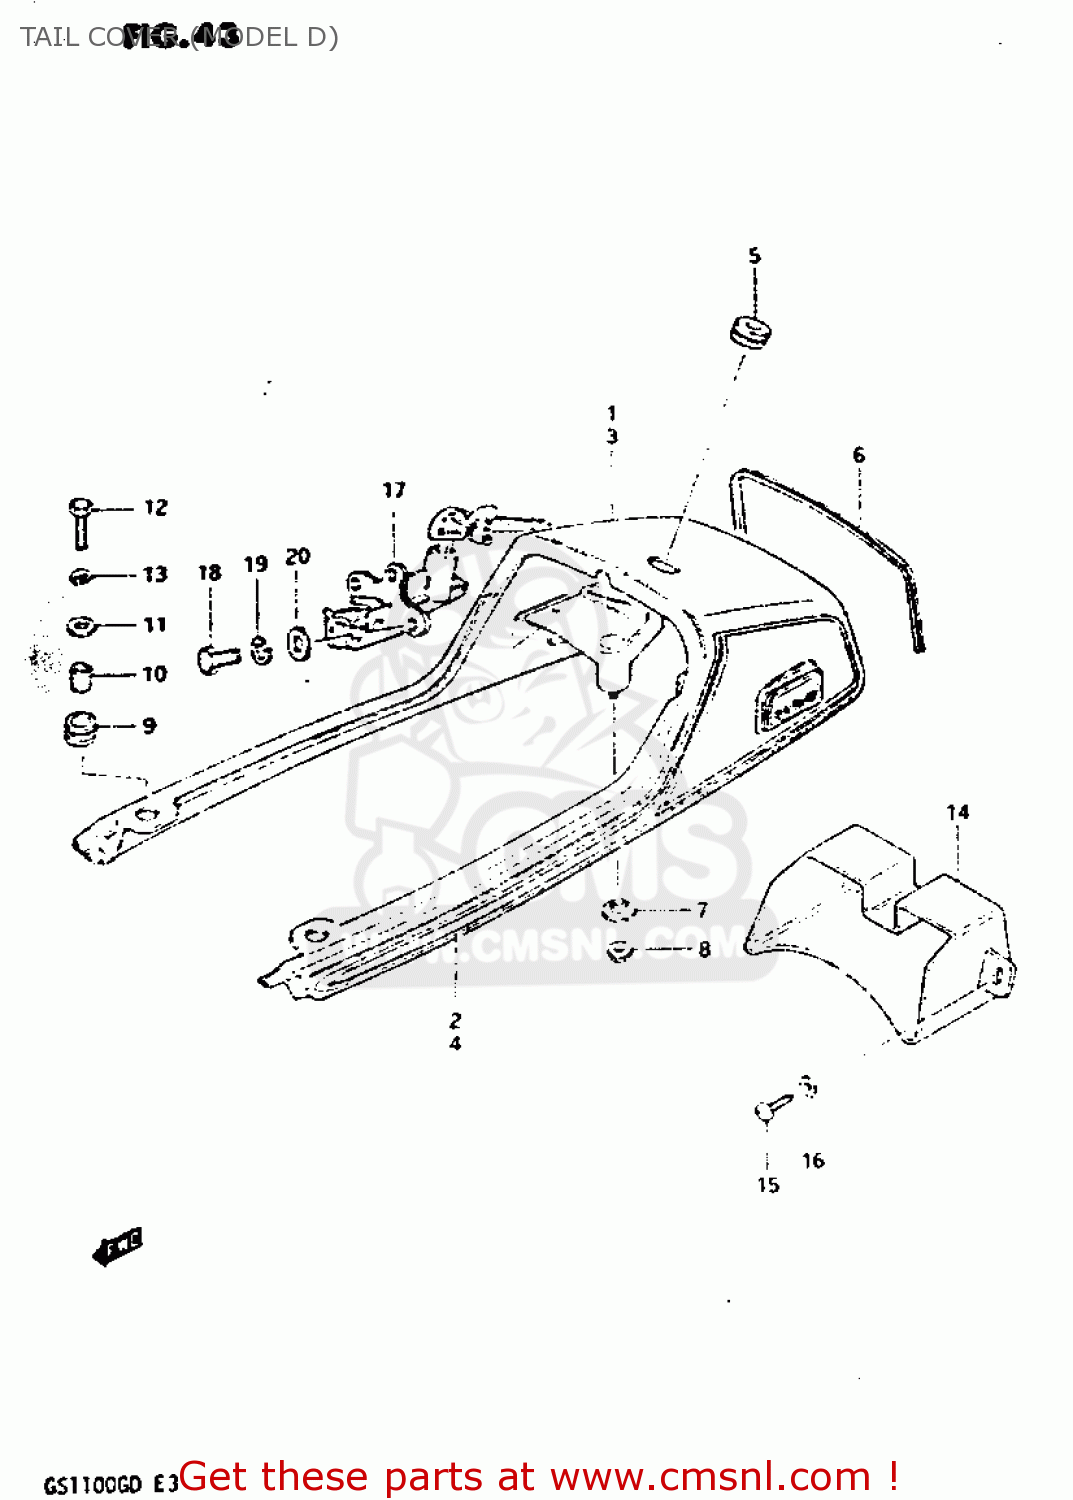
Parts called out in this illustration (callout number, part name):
1	COVER SET,SEAT TAIL
2	TAPE SET,SEAT TAIL COVER
3	COVER SET,SEAT TAIL
4	TAPE SET TAIL COVER
5	GROMMET,SEAT LOCK HOLE
6	MOLDING,SEAT TAIL COVER
7	WASHER
8	NUT 6MM
9	CUSHION
10	SPACER (7X10X12)
11	WASHER (6.5X24X1.6)
12	BOLT
13	WASHER,LOCK
14	BOX, SEAT TAIL
15	SCREW 6X12
16	WASHER,LOCK
17	LOCK SET,SEAT
18	BOLT
19	WASHER,LOCK
20	WASHER
